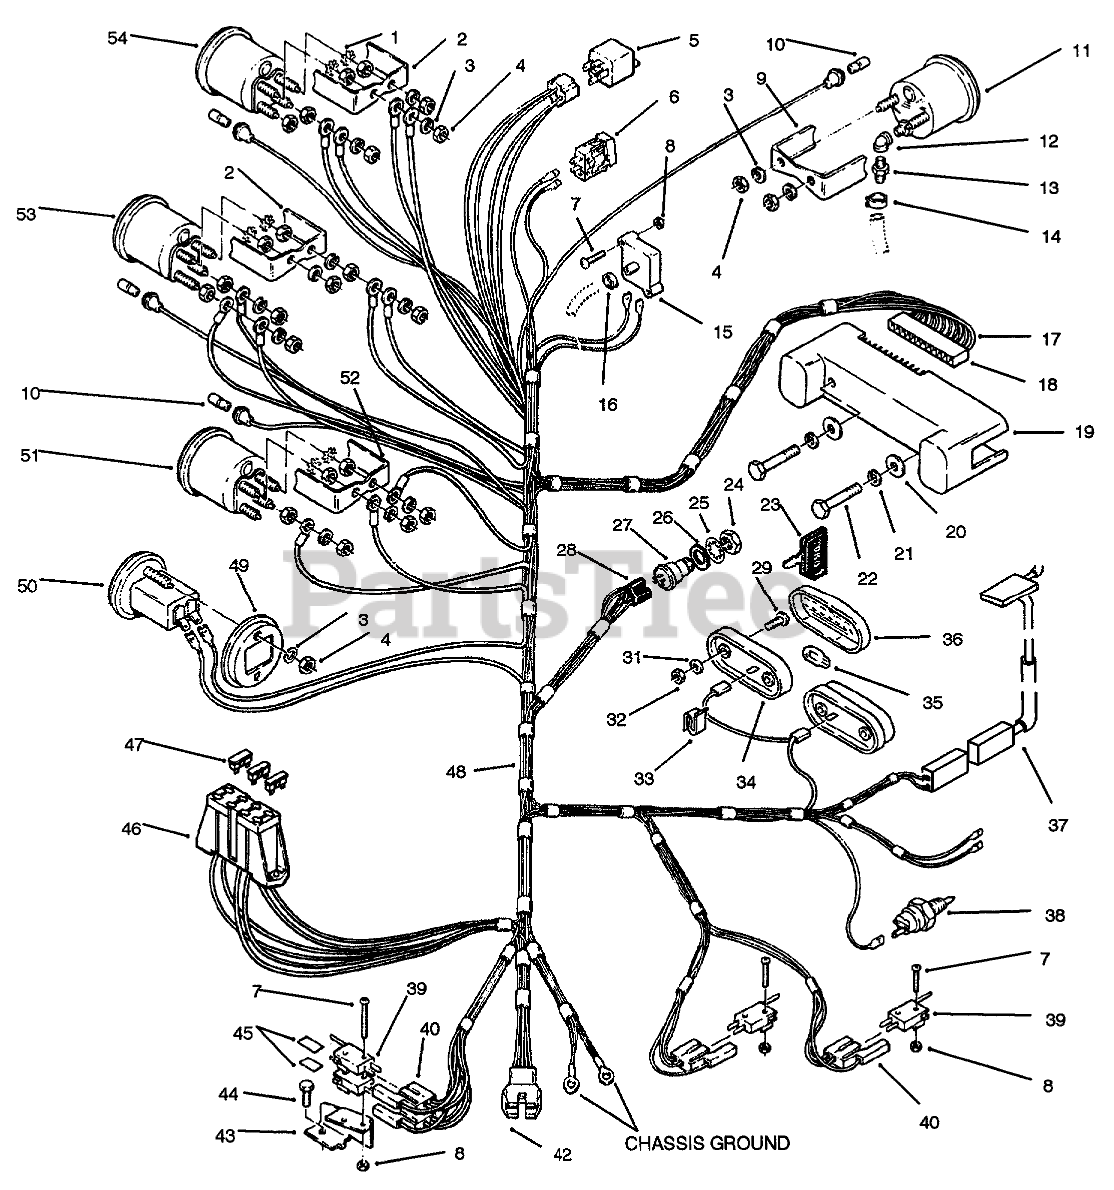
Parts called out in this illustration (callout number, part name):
1	WASHER-LOCK
2	CLAMP-MOUNTING
3	WASHER-LOCK
4	NUT-HEX
5	RELAY
6	SWITCH-HEADLIGHT
7	Screw
8	NUT HEX 4-40 ELAST
9	Bracket-Mounting
10	LAMP-MINIATURE GE 53X
11	Gauge-Vacuum (Incl. Ref. #3-4 & 9)
12	ELBOW
13	FITTING STRAIGHT
14	Clamp
15	ASSEMBLY - CHUTE W/DECAL
16	CLAMP-HOSE 5/16"
17	Terminal
18	Connector-Male
19	CIRCUIT-BRD 8 LIGHT
20	WASHER-FLAT
21	WASHER-LOCK
22	SCREW
23	KEY-IGNITION
25	WASHER-LOCK
26	Washer
27	Switch-ignition (Incl. Ref. #24-26)
28	CONNECTOR-5 WAY-SERV
29	Screw
31	WASHER-LOCK, INT
32	NUT-HEX
33	SPEED CLIP
34	BASE-TAIL LIGHT
35	LIGHT BULB
36	LENS-TAIL LIGHT
37	SWITCH-SEAT
38	SENSOR-HYDRO OIL HOT
39	SWITCH
40	CONNECTOR BODY
42	9-CIRCUIT CAP
43	Support-Switch
44	Bolt
45	BARRIER - SWITCH
46	FUSE-HOLDER 4 WAY
47	FUSE-BLADE, 10 AMP
48	WIRING-HARNESS & DIA
49	Bracket-Mountin
50	Hourmeter (Incl. Ref. #3-4 & 49)
51	Tachometer (Incl. Ref. #1, 3-4 & 5 52)
52	MOUNTING-BRACKET
53	Gauge-Fuel (Incl. Ref. #1-4)
54	Voltmeter (Incl. Ref. #1-4)
